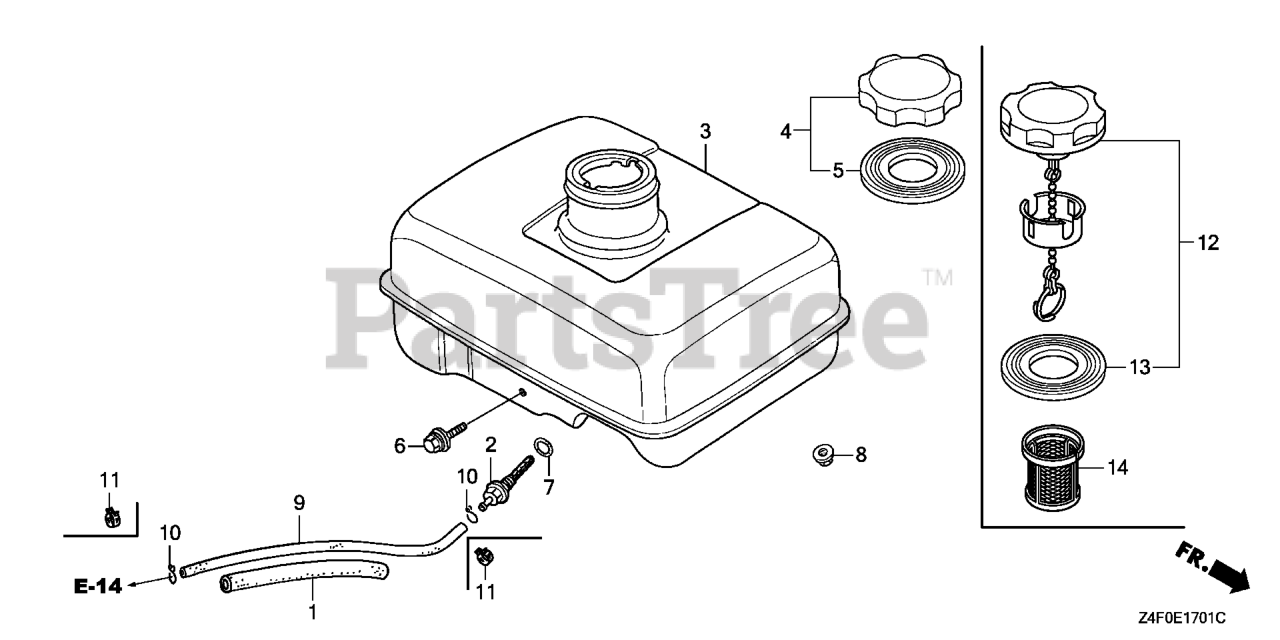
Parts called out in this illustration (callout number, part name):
1	RUBBER, SUPPORTER (107MM)
2	JOINT, FUEL TANK
3	TANK, FUEL *NH1* (BLACK)
6	BOLT, FLANGE (6X29)
7	O-RING (14MM) (ARAI) Use up to Engine SN 2949254.
8	NUT, FLANGE (6MM)
9	TUBE, FUEL (4.5X140) (FKM)
9	TUBE, FUEL (4.5X140)
11	CLIP, TUBE (D8)
12	CAP, FUEL FILLER
13	GASKET, FUEL FILLER CAP
14	FILTER, FUEL (FROM 1204807)
